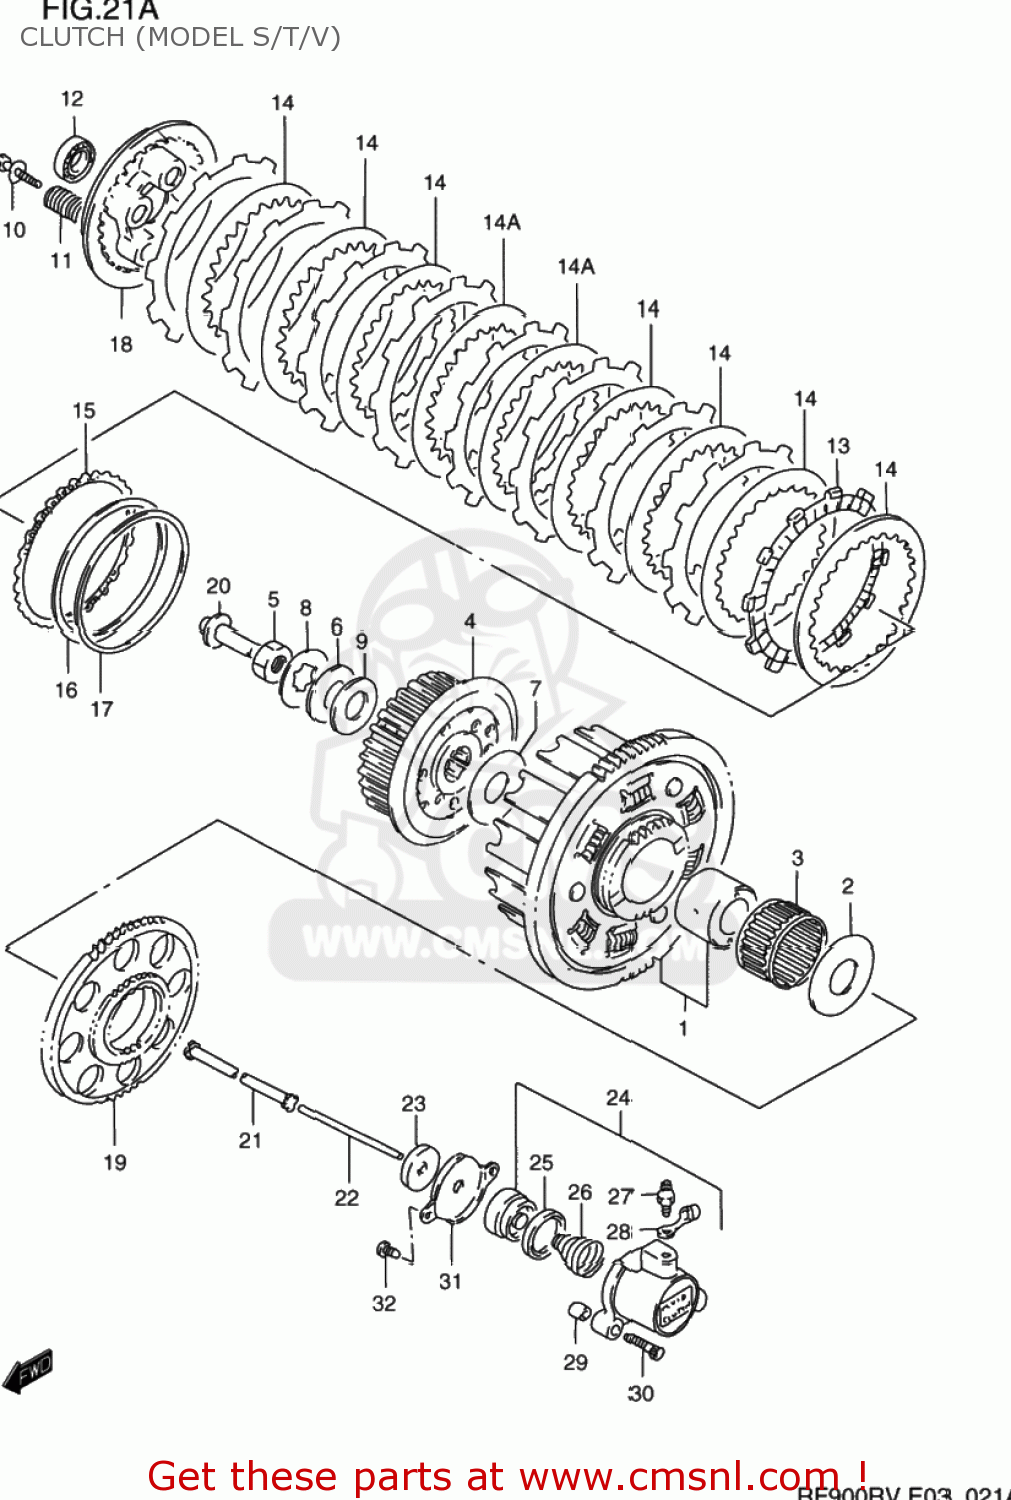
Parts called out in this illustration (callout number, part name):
1	GEAR ASSEMBLY,PRIMARY DRIVE
2	WASHER(25X54X2.5)
3	BEARING(35X40X35.8)
4	HUB,CLUTCH SLEEVE
5	NUT
6	WASHER
7	WASHER(25X50X2.5)
8	WASHER,LOCK
9	WASHER
10	BOLT,CLUTCH SPRING
11	SPRING,CLUTCH
12	BALL BEARING
13	PLATE,CLUTCH DRIVE
14	PLATE,CLUTCH DRIVEN NO.1
14A	PLATE,CLUTCH DRIVEN NO.2
15	PLATE,CLUTCH DRIVE
16	WASHER,CLUTCH PLATE
17	SEAT,CLUTCH PLATE WAVE WASHER
18	DISC,CLUTCH PRESSURE
19	GEAR,GENERATOR DRIVE
20	PIECE,CLUTCH PUSH
21	ROD,CLUTCH
22	ROD,CLUTCH PUSH
23	SEAL,OIL(6X34X5.5)
24	CYLINDER,CLUTCH RELEASE
25	CUP
26	SPRING,CLUTCH CYLINDER
27	BLEEDER
28	CAP,BLEEDER
29	PIN
30	BOLT,CL.COVER
31	COVER,CLUTCH RELEASE CYLINDER
32	SCREW
